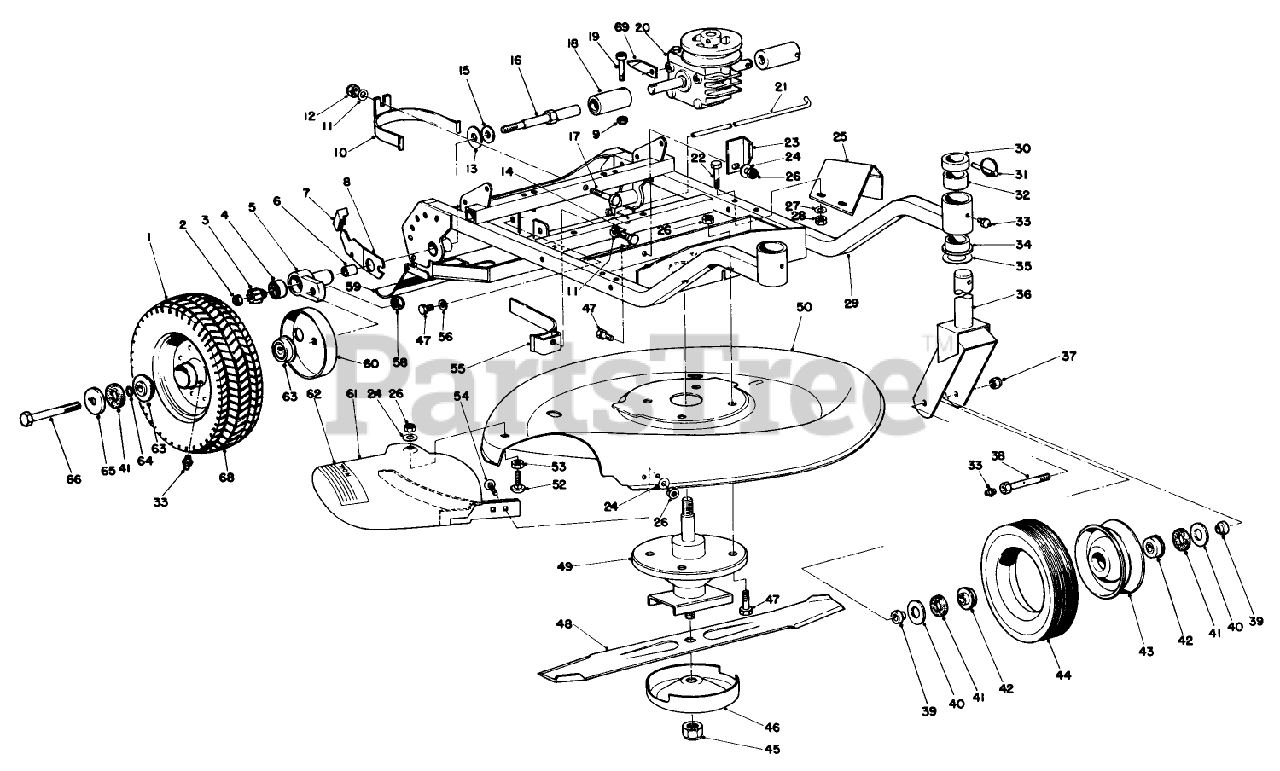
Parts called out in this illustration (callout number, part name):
1	HOOD IN CARTON
2	REAR HOOD FOAM STRIP
4	WASHER-FLAT
7	WASHER-SPRING
9	SCREW-HH
13	SCREW-HH
14	NUT-HEX
15	WASHER-FLAT
16	SCREW-SHOULDER
17	NUT-HEX
18	NUT-HF
22	NUT-LOCK, NI
24	HOOD TRIM
25	TRIM-HOOD
